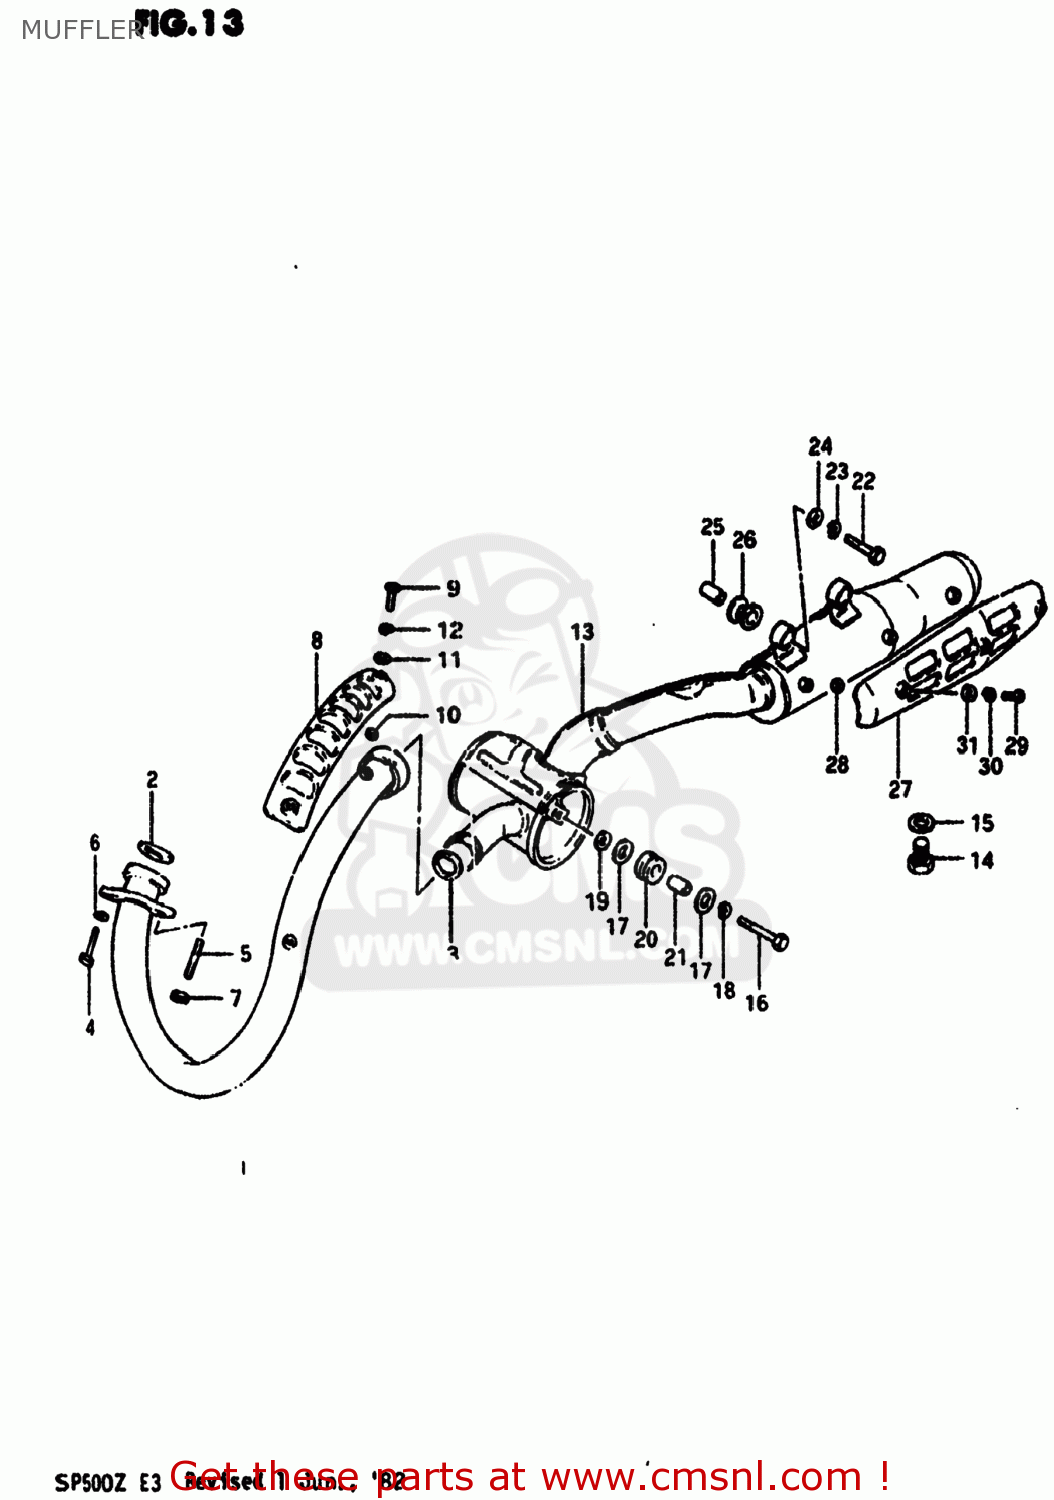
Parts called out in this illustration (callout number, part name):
1	PIPE,EXHAUST
2	GASKET,EXHAUST PIPE (NAS)
3	GASKET,EXHAUST PIPE (NAS)
4	BOLT
5	STUD 8X20
6	LOCK WASHER
7	NUT
8	COVER,EXHAUST PIPE
9	SCREW 6X12
10	GASKET 6.2X12X1.5 (MCA)
11	WASHER
12	LOCK WASHER
13	MUFFLER ASSEMBLY
14	PLUG(12X9)
15	GASKET(12X16X2) (NAS)
16	BOLT
17	WASHER (8.5X29X1.6)
18	LOCK WASHER
19	GASKET
20	CUSHION
21	SPACER (8.6X13.8X13)
22	BOLT 8X40
23	LOCK WASHER
24	WASHER (8.5X29X1.6)
25	SPACER
26	CUSHION
27	COVER,SECOND MUFFLER
28	GASKET 6.2X12X1.5 (MCA)
29	SCREW 6X12
30	LOCK WASHER
31	WASHER
